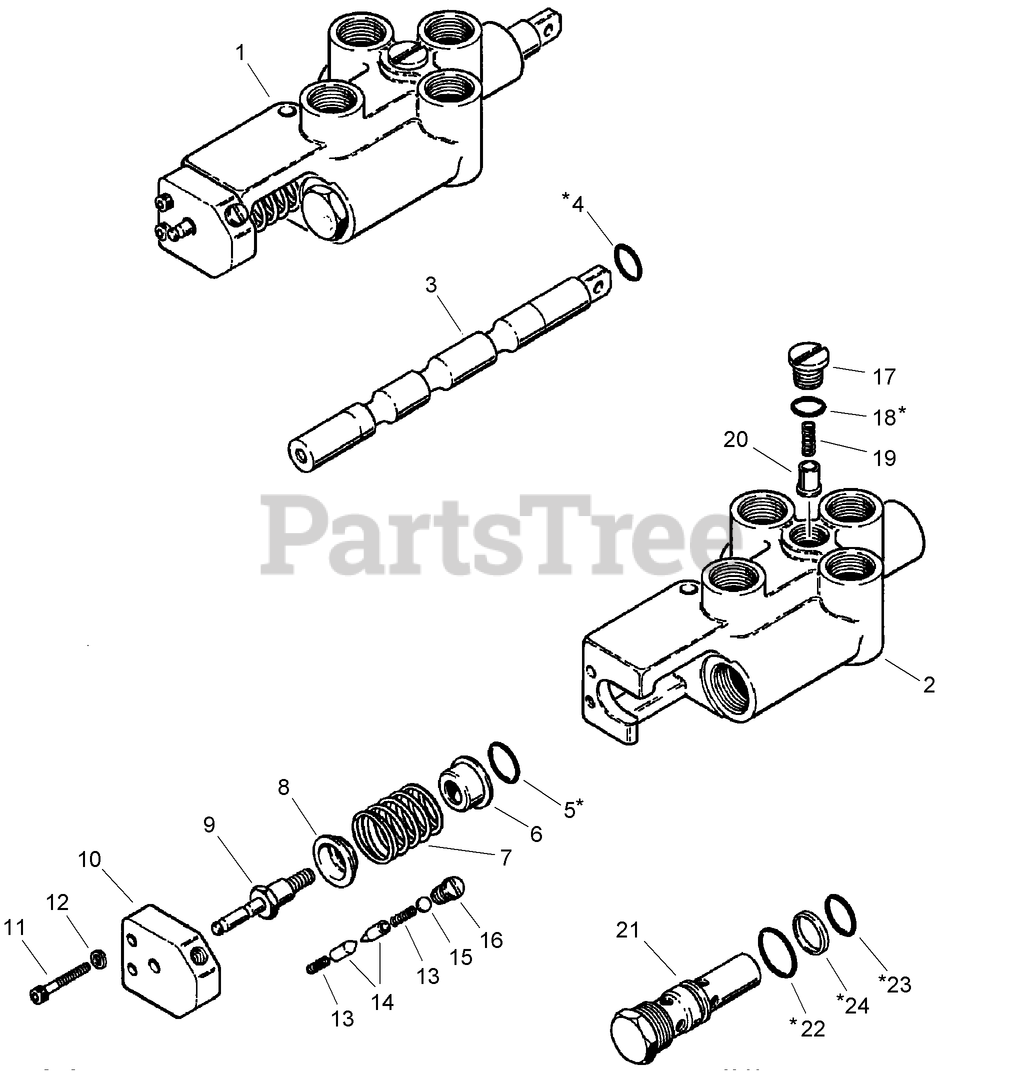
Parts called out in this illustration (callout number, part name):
1	HYD VALVE ASM
2	BODY - Control Valve
3	SPOOL - Control Valve
4	O-RING - Spool, Spool Eye End
5	O-RING
6	RETAINER - Spring, Inner
7	SPRING - Centering, Spool
8	SEAT - Spring, Outer
9	SCREW - Spool End, Detent
10	BLOCK - Detent
11	SCREW - Machine, Pan Head Slotted, 1/4 NC x 1 inch
12	WASHER-Spring Lock Reg 0.250 in ZND
13	SPRING - Detent
14	DETENT - Spool, Detent
15	DISC - Detent
16	PLUG - Detent
17	PLUG - Load Check
18	O-RING - 1/2 ID x 3/32 inch Wide
19	SPRING - Load Check Valve
20	POPPET - Load Check Valve
21	VALVE - Relief, Control Valve
22	O-RING-3/4 ID x 3/32 inch wide
23	O-RING
24	RING - Backup, Plug O-Ring
